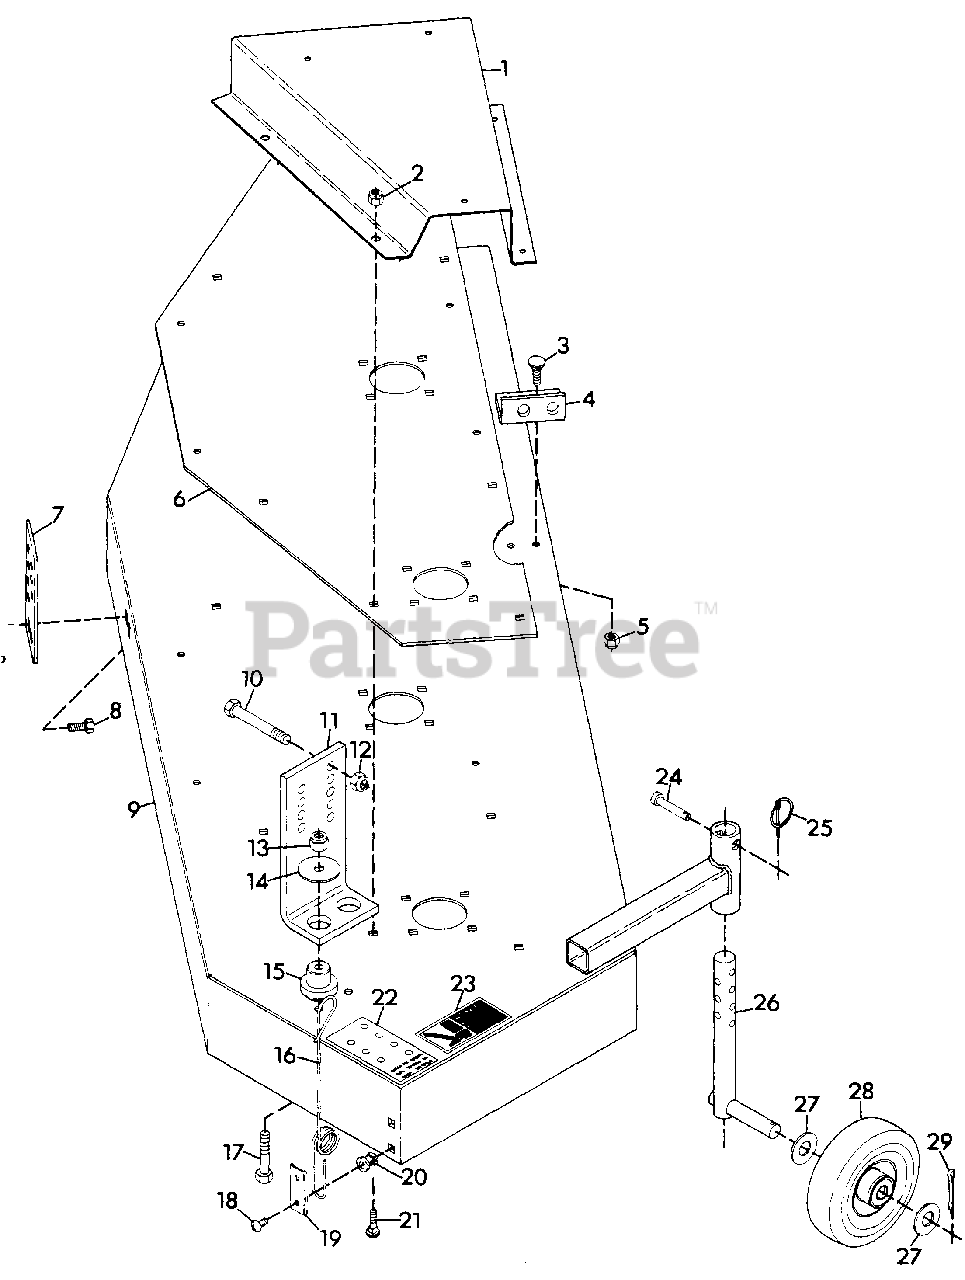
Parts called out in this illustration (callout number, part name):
1	HOUSING, BEARING
2	PLATE, ENGINE
3	KEY, SQUARE 1/4X1
4	CLUTCH, ROTOR ASM.
5	SCREW, SET 1/4-20X.375 HSCP
6	SPACER, ENGINE
7	BOLT, HEX 5/16-18X4.75
8	V-BELT, DRIVEN
9	BOLT, HEX M10X1.50X25MM
10	WELDMENT, IDLER R.H.
11	ROD, IDLER R.H.
12	NUT, HEX 3/8-16
13	WASHER, FLAT .406X.812X.065
14	SLEEVE, SPRING FOR.-REV.
15	SPRING, IDLER COMPRESSION
16	NUT, LOCK 3/8-16
17	PULLEY, V-IDLER
18	BOLT, HEX 3/8-16X1.75
19	ROD, IDLER L.H.
20	PIN, COTTER 3/32X1.00
21	WASHER, LOCK 7/16 REG.
22	BELT, 40 INCH MOWER
23	NUT, LOCK 5/16-18
24	SHAFT, SPINDLE
25	BOLT, HEX M8X1.25 25MM
26	WASHER, FLAT .500X1.250X.083
27	SHEAVE, IDLER
28	FITTING, LUBE 1/4-28
29	BOLT, HEX 3/8-16X2.00
30	WELDMENT, IDLER L.H.
31	SHEAVE, SPINDLE
32	PULLEY, CENTER
33	PULLEY, L.H.
34	SEAL, STEEL
35	WASHER, FLAT .975X1.970X.030
36	ASSEMBLY, BEARING
37	NUT, LOCK 1/4-20
38	WELDMENT, BLADE CRADLE
39	BLADE
40	FITTING, LUBE 1/8 PIPE 90 DEG.
41	NUT, LOCK 5/8-11
42	SPRING, BELLEVILLE
43	BOLT, HEX M8X1.25X140MM
44	SPINDLE ASSEMBLY
45	BOLT, 3/8-16X1.25 RD HD SQ NK
46	WASHER, LOCK 8MM SPRING
47	RING, RETAINING INTERNAL SPIRAL
48	BEARING, BALL 2.677X1.574X.590
49	HOUSING, CLUTCH
50	RING, RETAINING EXTERNAL SPIRAL
51	NUT, LOCK 1/4-20
52	ENGINE, KAWASAKI SPEC. ES01
53	WIRE, THROTTLE
54	PLATE, THROTTLE
55	WASHER, FRICTION
56	WASHER, SPRING
57	ASSEMBLY, KNOB AND LEVER
58	SCREW, MACHINE 1/4-20X.50
59	BOLT, HEX 1/4-20X.75
